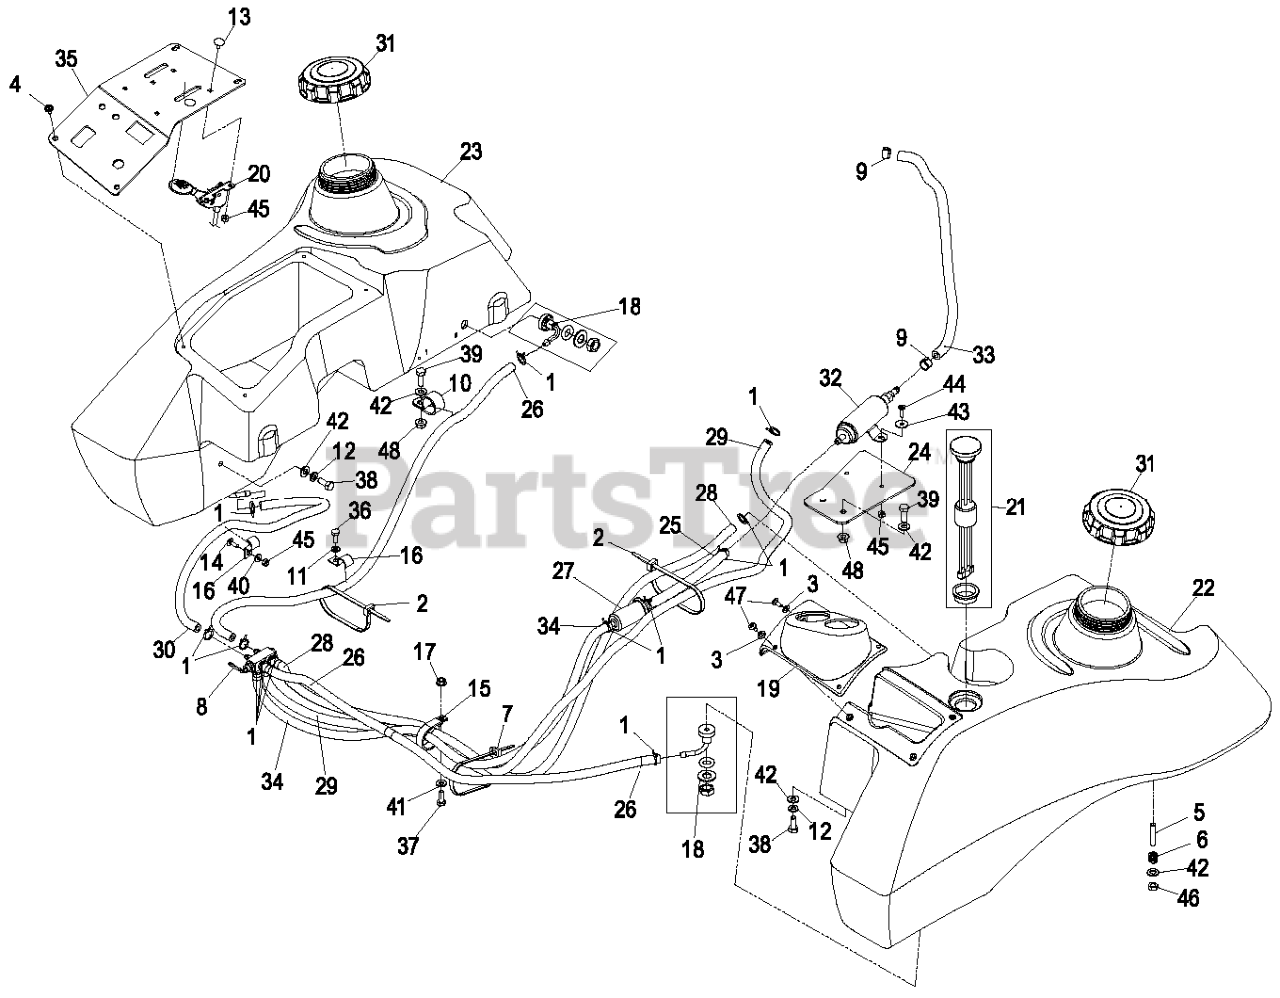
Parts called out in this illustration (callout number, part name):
2	TIE-PLASTIC
3	WASHER-SPRING
4	SCREW-PPH
5	STUD
6	SPRING-TANK, FUEL
7	TIE-PLASTIC
8	VALVE-FUEL, DUAL FLOW
9	CLAMP-HOSE, FUEL
10	CLIP-LOOM
11	WASHER-LOCK
12	WASHER-LOCK
13	BOLT-CARR
14	BOLT-CARR
15	CLIP-LOOM
16	CLIP-HALF, LOOM
18	FITTING-FUEL, BULKHEAD
19	BEZEL, GAGE XP LH TANK
20	CONTROL-THROTTLE
21	KIT, CT FUEL GAGE REPL.
24	BRACKET, FUEL PUMP
25	HOSE-FUEL
26	HOSE-FUEL
27	P/N 49019-1055 Fuel, Filter
28	HOSE-FUEL
29	HOSE-FUEL
30	HOSE-FUEL
31	CAP-FUEL, GAS
32	PUMP-FUEL
33	KIT,FUEL LINE W/ CLAMPS
34	HOSE-FUEL
35	PANEL,CONTROL W/DECALS
36	SCREW-HH
37	SCREW-HH
38	SCREW-HH
39	SCREW-HH
40	WASHER-FLAT
41	WASHER-FLAT
42	WASHER-PLAIN
43	WASHER-FLAT
44	SCREW-PPH
45	NUT-LOCK, NI
46	NUT-LOCK, NI
47	SCREW-PTH
